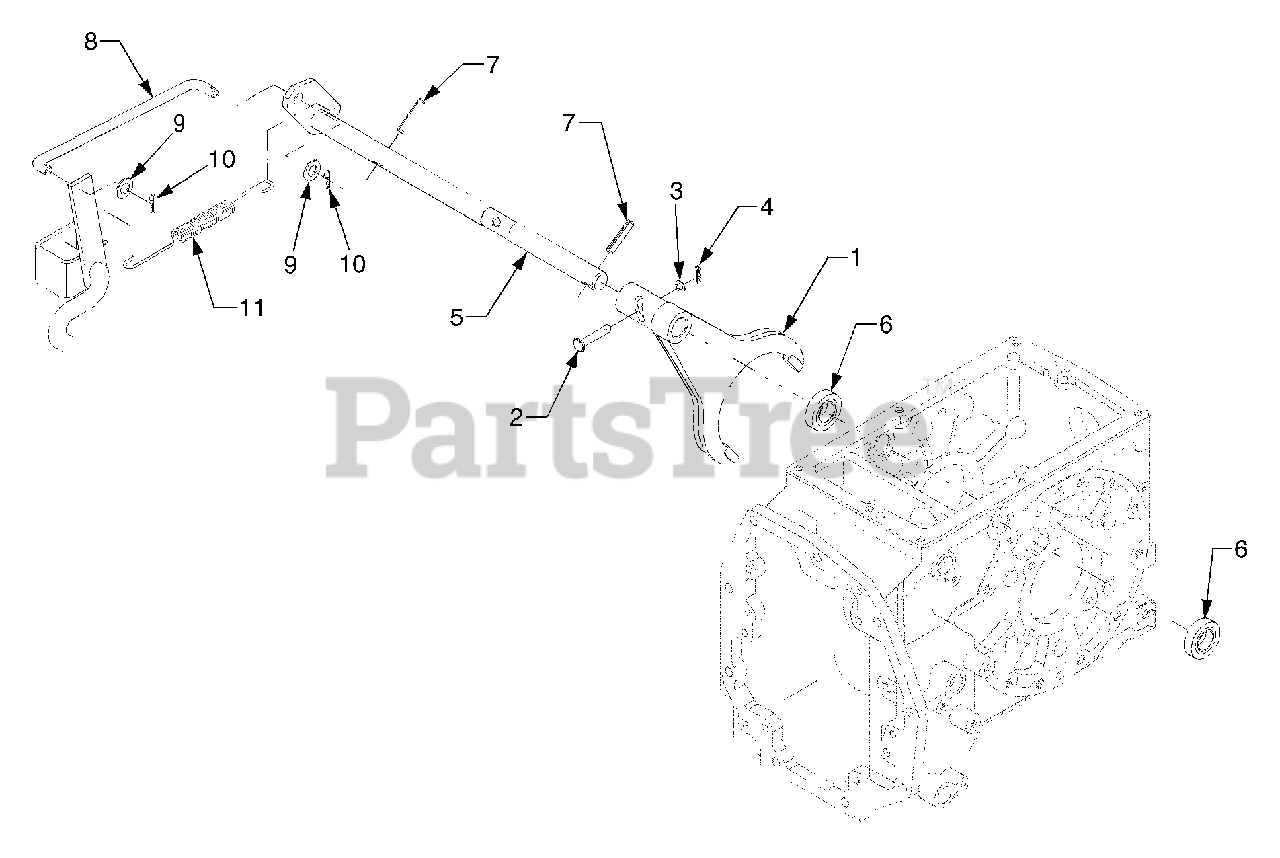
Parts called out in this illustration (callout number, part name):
1	Fork, Differential Lock
3	Washer, Plain
5	Shaft, Differential Lock
8	Rod, Differential Lock
9	Washer, Plain
